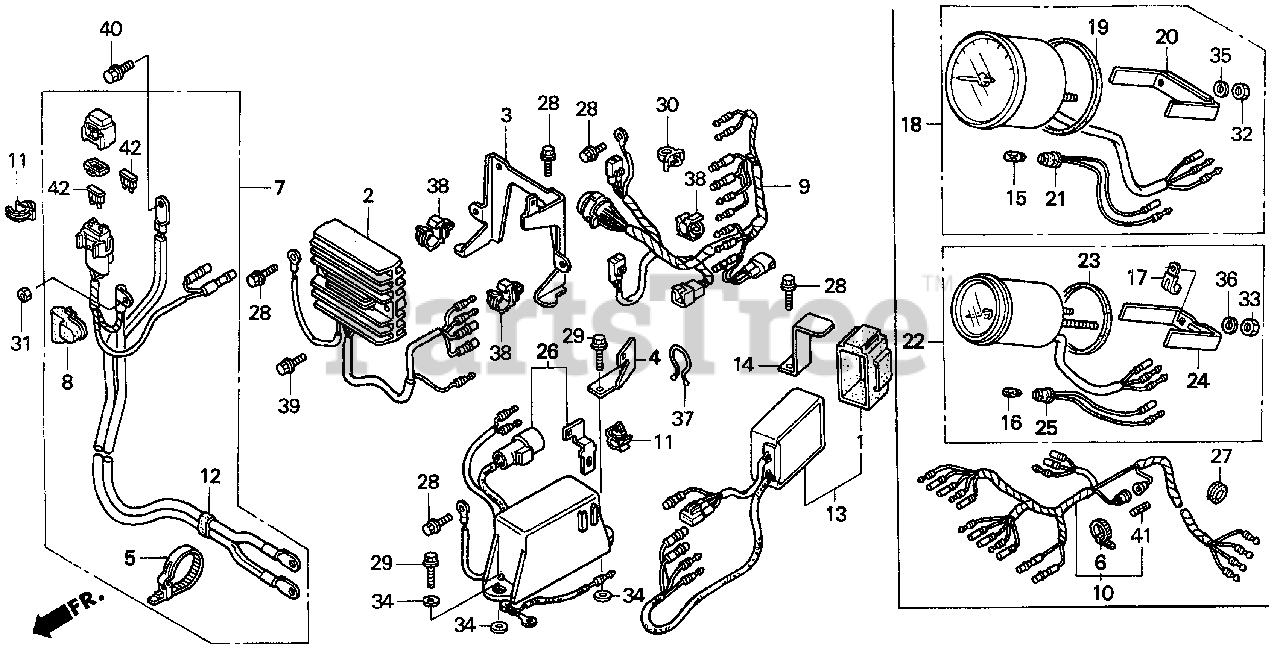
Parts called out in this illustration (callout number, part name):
1	RUBBER, IGNITION CONTROL MODULE
2	RECTIFIER ASSY., REGULATOR (12A)
3	BRACKET, REGULATOR
4	BRACKET, HARNESS CLIP
5	BAND, WIRE
6	BAND B1, WIRE
7	CABLE ASSY., STARTER
8	COVER, TERMINAL
9	CABLE ASSY., REMOTE CONTROL (A)
10	HARNESS ASSY., METER (A)
11	CLAMP, WIRE
12	CLAMP, IGNITION WIRE
13	CONTROL UNIT, TRIM
14	BRACKET, UNIT
15	BULB, WEDGE BASE (12V 1.7W)
16	BULB, WEDGE BASE (12V 1.7W)
18	TACHOMETER ASSY.
22	METER ASSY., TRIM
26	RELAY ASSY., POWER TILT
28	BOLT, FLANGE (6X12)
29	BOLT, FLANGE (6X18)
30	HOLDER, ROD (6MM)
31	NUT, HEX. (6MM)
32	NUT, HEX. (5MM)
33	NUT, HEX. (4MM)
34	WASHER, PLAIN (6MM)
34	WASHER (6MM)
35	WASHER, SPRING (5MM)
36	WASHER, SPRING (4MM)
37	CLIP, PURSE LOCK
38	CLIP, WIRE HARNESS
39	BOLT, FLANGE (6X20)
40	BOLT, FLANGE (8X12)
41	FUSE A (10A)
42	FUSE, BLADE (15A)
